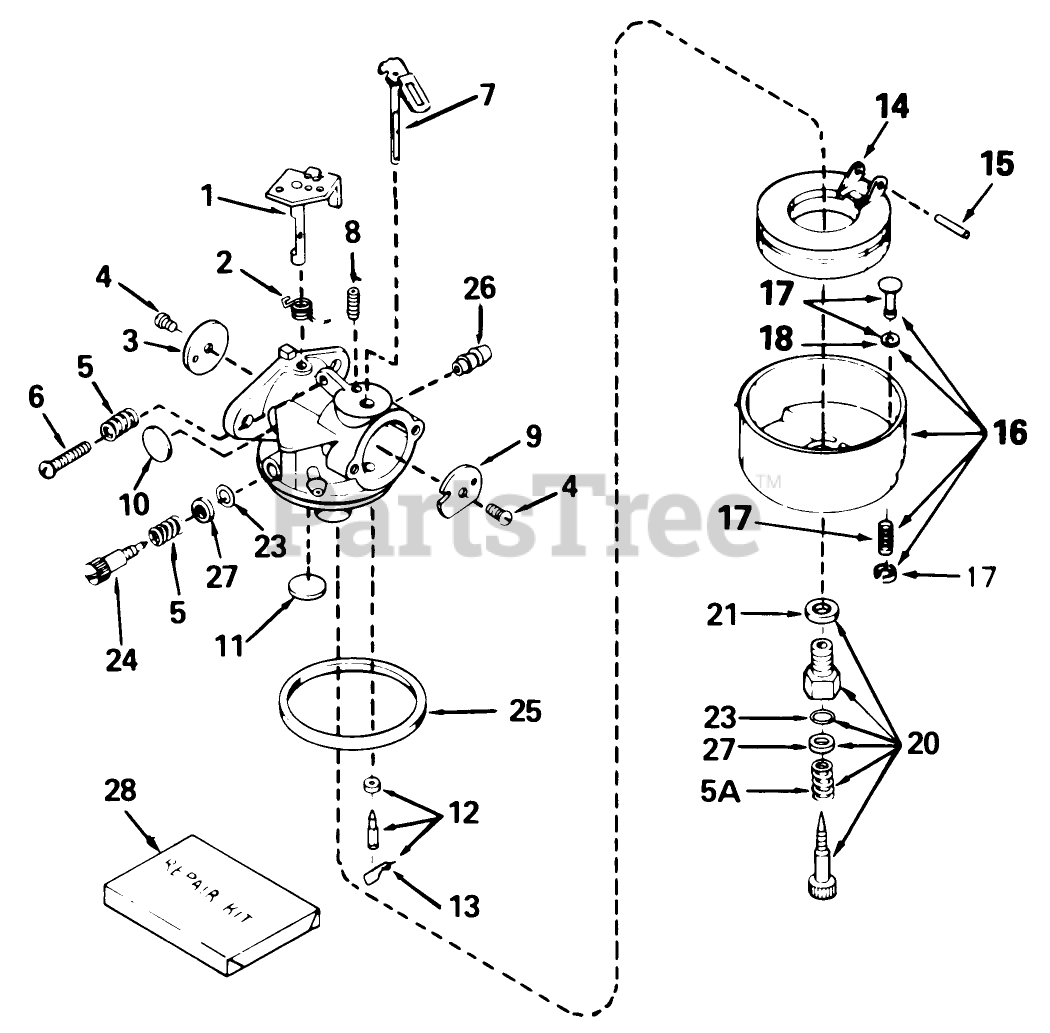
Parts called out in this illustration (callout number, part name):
1	Throttle Shaft and Lever ASM
2	Spring-Return, Throttle
3	Shutter-Throttle
4	Screw-Shutter
5	Spring-Tension
5A	Spring
6	Screw-Throttle Crack Screw / Idle Speed
7	Choke Shaft and Lever ASM
8	Spring-Positioning, Choke
9	Shutter-Choke
10	Plug-Welch, Idle Mixture Well
11	Plug-Welch, Atmospheric Vent
12	Inlet Needle, Seat Clip Assy. (Incl. No. 13)
13	Clip-Spring
14	Float
15	Shaft-Float
16	Float Bowl Asm. (Incl. Ref. # 32, 33)
17	Bowl Drain ASM
18	Gasket-Plunger, Drain
20	Adjustment Screw Assy.,Main (Incl. Ref. #5A,21,23 30)
21	Washer-Bowl Nut
23	ORing
24	Screw-Idle Mix
25	O Ring-Bowl, Float
26	Fitting-Fuel
27	Washer
28	Kit-Repair
